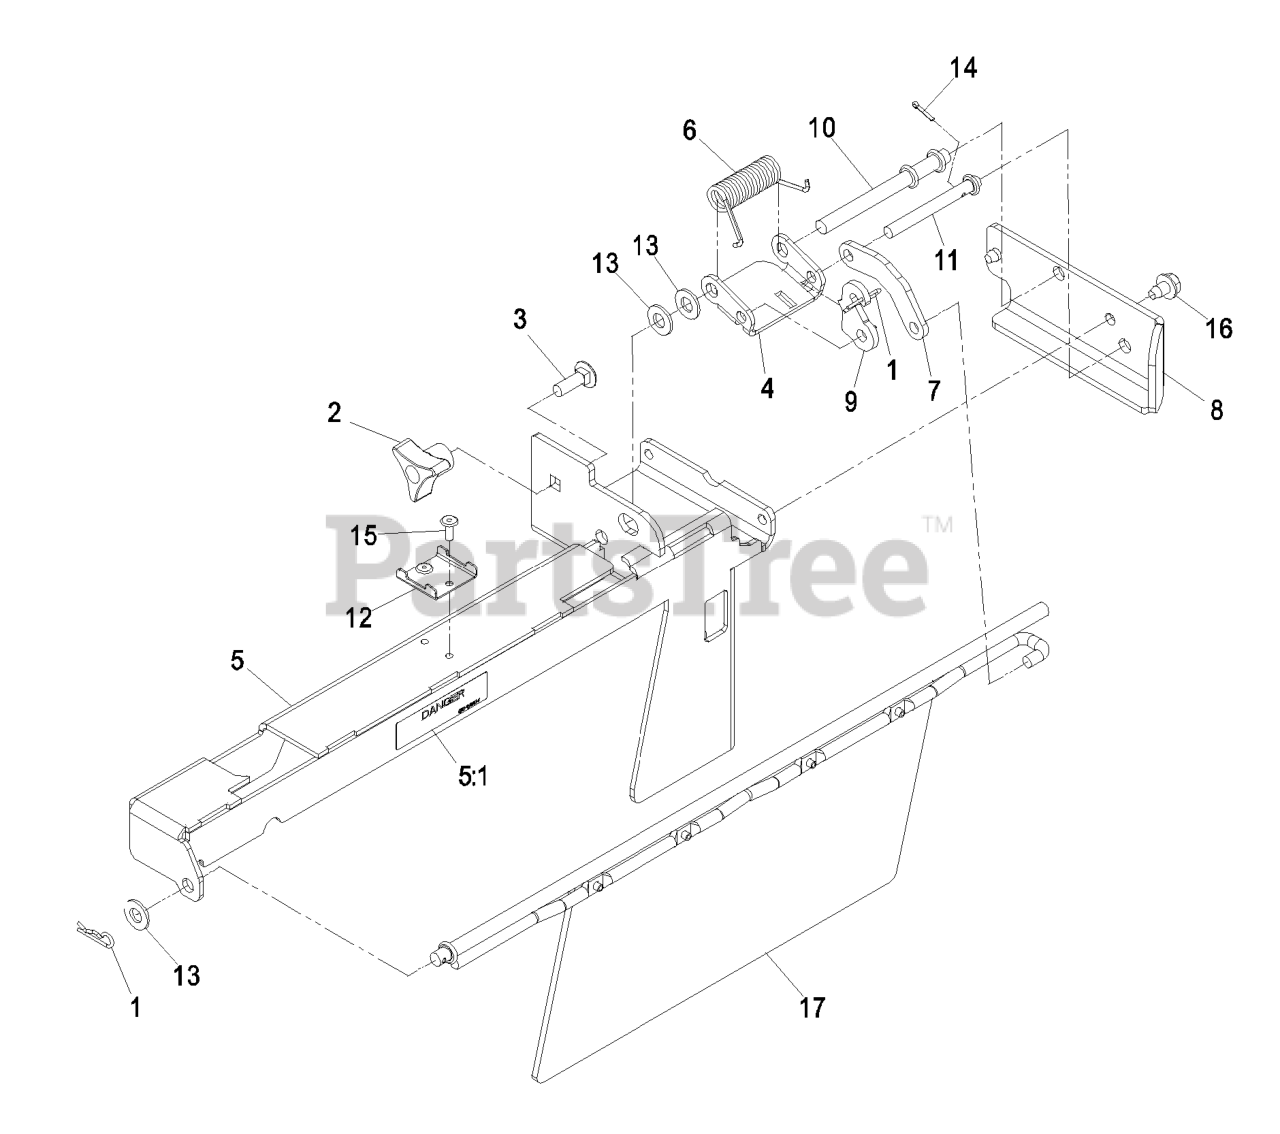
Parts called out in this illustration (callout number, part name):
1	Hairpin, Cotter
2	Knob, 3 Prong
3	Bolt, Carriage 5/16-18 X 1
4	Bracket, Link Pivot
5	Asm, Gate Link Frame W/Decal
5:1	Decal, Danger
6	Spring-Torsion
7	Link, Gate
8	Bracket, Pivot Support
9	Link, Gate Lift
10	Rod, Control Pivot
11	Rod, Control Link
12	Channel, Latch Contact
13	Washer, 3/8 SAE
14	Pin, Cotter 3/32 X 1/2
16	Screw, Hwh 5/16 X 1/2 Tf
17	Asm, Gate
